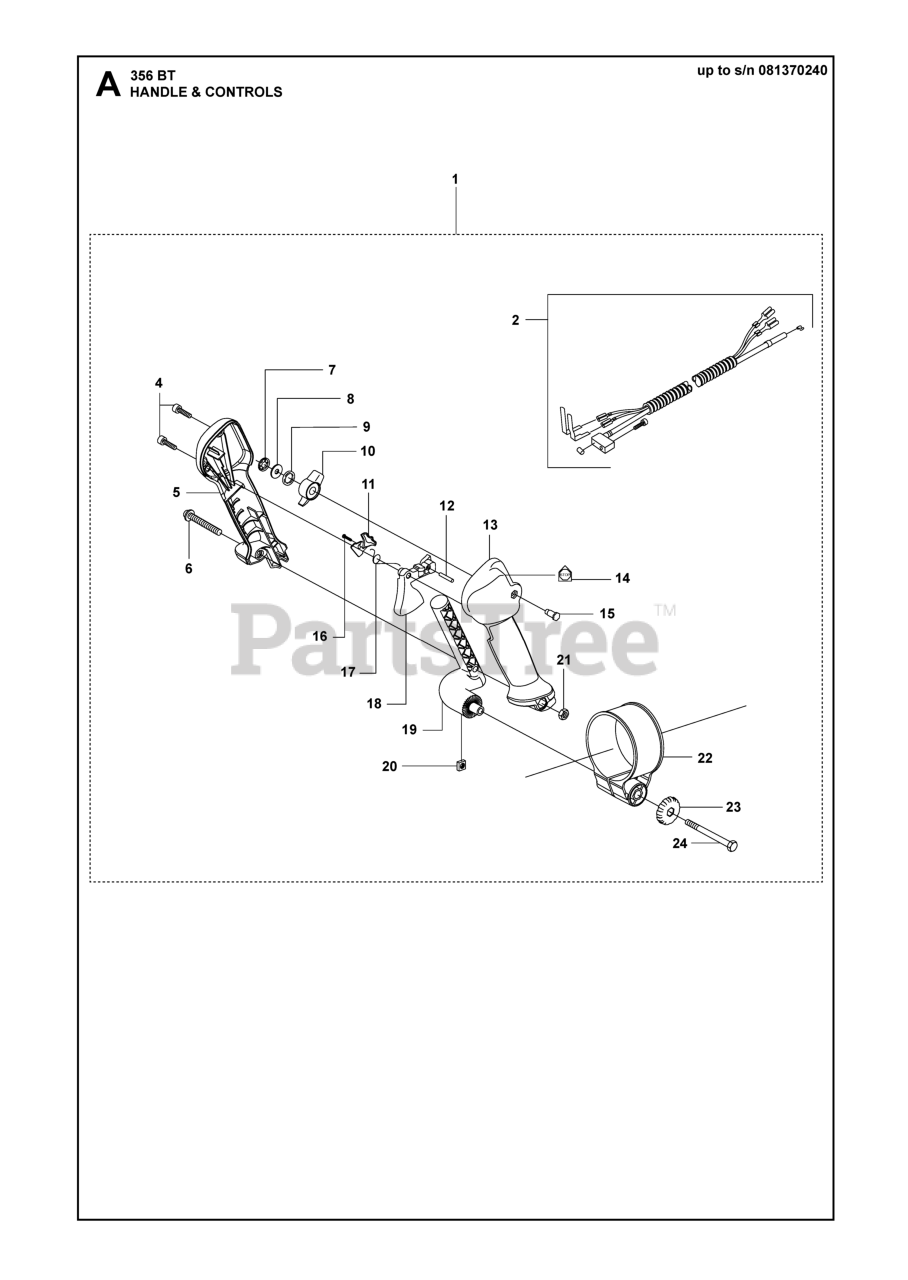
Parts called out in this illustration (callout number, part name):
1	HANDLE ASSY
2	WIRING ASSY
6	SCREW
9	SPRING RUBBER
18	THROTTLE TRIGGER
19	BRACKET
